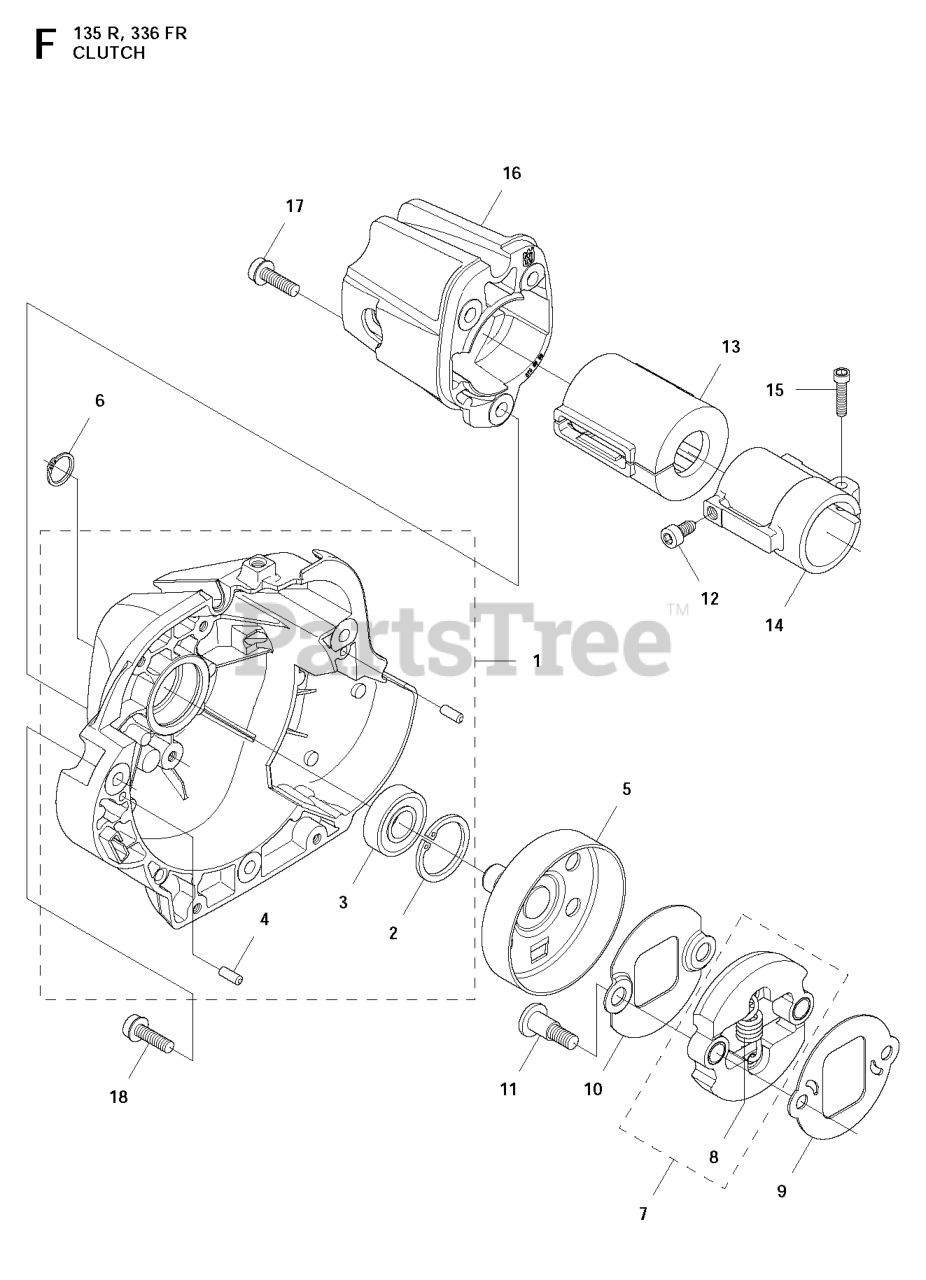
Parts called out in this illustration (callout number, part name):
1	CLUTCH COVER ASSY KPL HUSQVARN
2	RETAINING RING SGH 28
3	BALL BEARING
5	CLUTCH DRUM
6	SEEGER CLIP
7	CLUTCH CPL
9	WASHER
11	SCREW CLUTCH
12	SCREW IHSCT
13	VIBRATION ABSORBER
14	SLEEVE, COVER
15	SCREW MC6S 5X25
18	SCREW CLUTCH
